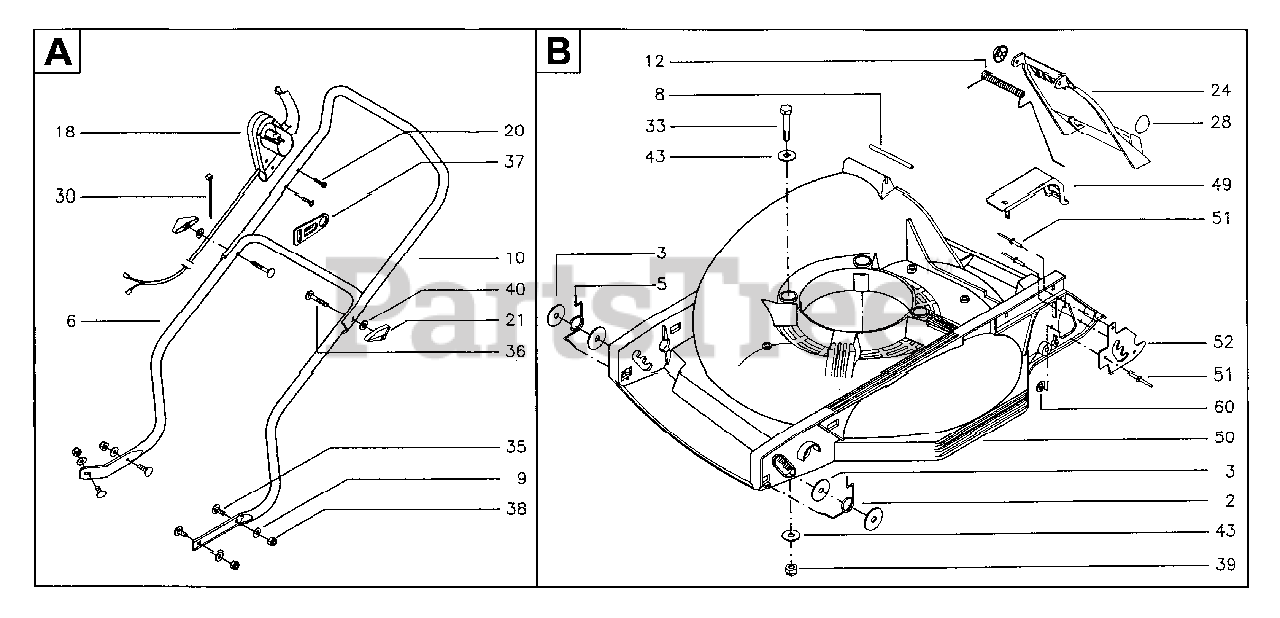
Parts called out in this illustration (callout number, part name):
38	LOCKNUT M6
39	LOCKNUT M8
40	WASHER - 15X7.3X1.6
60	WASHER
